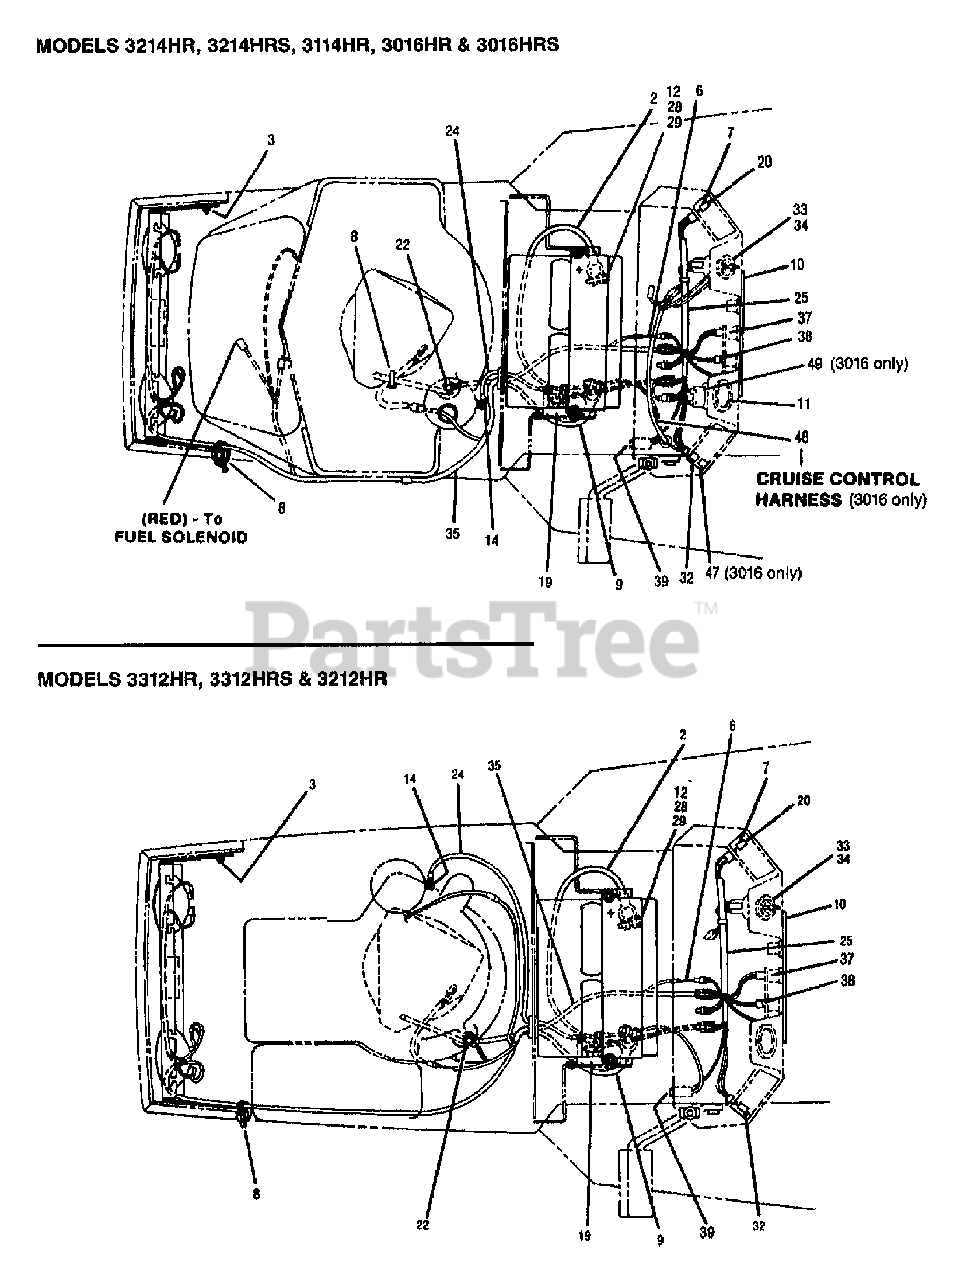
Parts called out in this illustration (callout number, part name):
1	HARNESS-ACTUATOR {3214HR,3114HR}
2	CABLE-BATTERY (+)
3	NUT-HF/LK 1/4-20 ZP
4	SUPPORT-LIGHT
5	HEADLAMP
6	ASSM-DIODE {3214HR,3114HR,3312HR,3212HR}
7	SWITCH-ELEC LIFT {3214HR,3114HR}
8	TIE-CABLE NYLON BLACK
9	CABLE-BATTERY (-)
10	LENSE
10	LENSE-INST PANEL TRACTOR {3016HR,3016HRS}
11	METER-HOUR (TRACTOR)
14	NUT-HT LK 1/4-20
15	BOLT-HOOK
17	NUT W/LKWASHER 10-24 ZP
18	BATTERY
19	SOLENOID
20	SCR-FHP #6-32X.50 ZP
21	RETAINER
23	GROMMET-SPLIT
24	CABLE-STARTER {3214HR,3114HR,3016HR,3016HRS}
24	CABLE-STARTER {3312HR,3212HR}
25	HARNESS-CONSOLE WIRING
26	CLIP-J
27	PAD-RUBBER
30	HARNESS-INTERLOCK {3214HR,3114HR,3312HR, 3212HR}
30	HARNESS-INTERLOCK {3016HR,3016HRS}
31	SWITCH-PTO
32	SWITCH-LIGHT
33	SWITCH-IGNITION
34	KEY-IGNITION
35	HARNESS-ENGINE {3214HR,3114HR}
35	HARNESS-WIRE ENGINE {3312HR,3212HR}
35	HARNESS {3016HR,3016HRS}
36	BATTERY-HOLDDOWN
37	BULB (MFG NO. GE 73)
38	SCR-PHP M6-32X.38 ZP
39	FUSE-30 AMP
40	GROMMET
41	SWITCH
42	HARNESS-ELEC LIFT {3214HR,3114HR}
43	SCR-PHP 1/4-20X.50 ZP
44	SWITCH-SEAT
47	SWITCH-SPEED CONTROL {3016HR,3016HRS}
48	HARNESS, CRUISE
49	RELAY-SPEED CONTROL {3016HR,3016HRS}
50	BLOCK {3016HR,3016HRS}
51	SCR-HHS 10-24X.625 ZP {3016HR,3016HRS}
52	SWITCH {3016HR,3016HRS}
